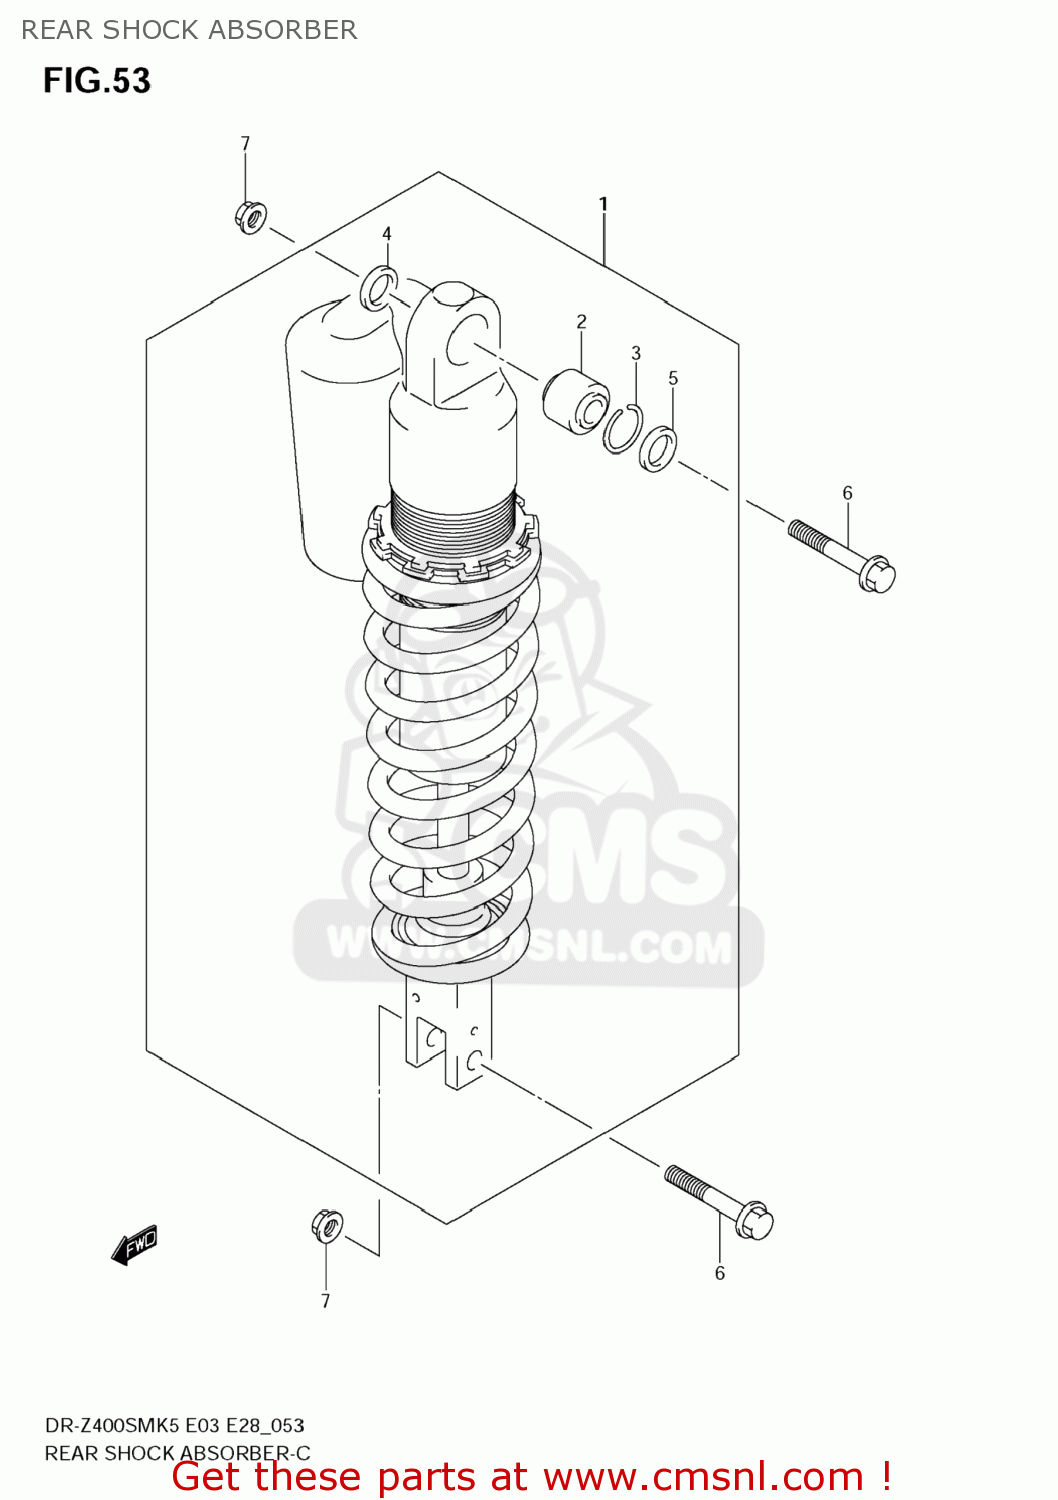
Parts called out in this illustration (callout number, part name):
1	ABSORBER ASSY,RR SHOCK
2	BEARING,RR SHOCK ABSORBER
3	RING,STOPPER
4	SEAL,DUST UPR,R
5	SEAL,DUST UPR,L
6	BOLT(10X47.5)
7	NUT
